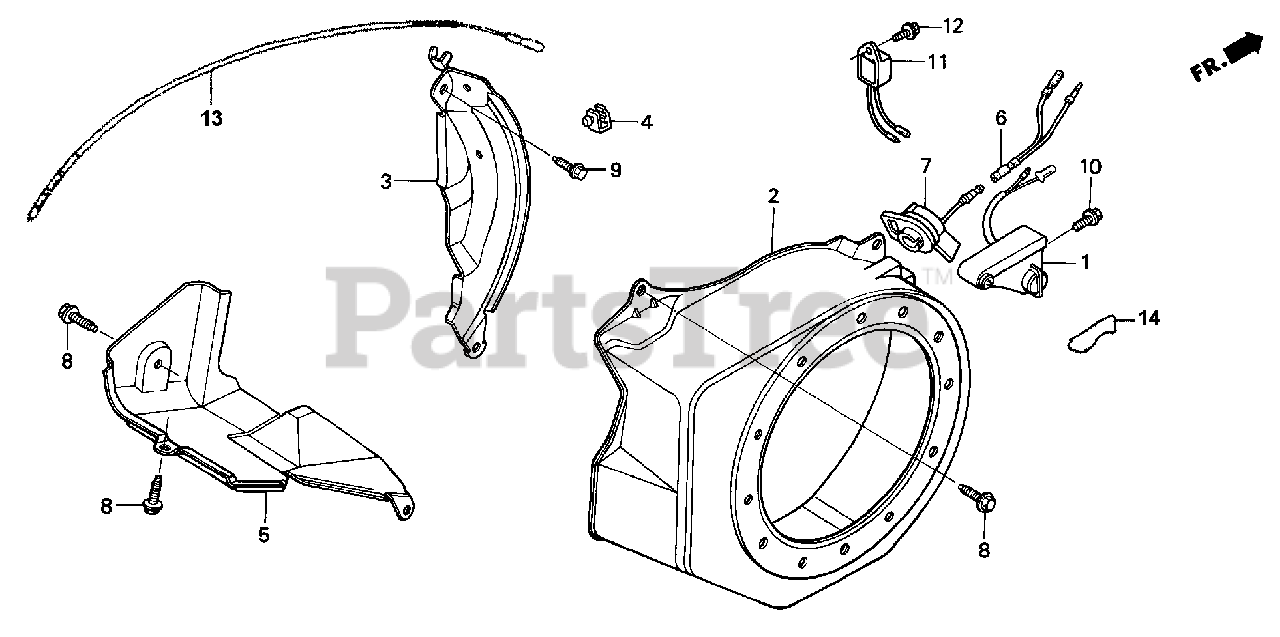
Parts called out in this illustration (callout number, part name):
1	ALERT UNIT, OIL
2	COVER, FAN *R8* (BRIGHT RED)
2	COVER, FAN *R280* (POWER RED)
2	COVER, FAN *R8* (OIL ALERT) (BRIGHT RED)
2	COVER, FAN *R280* (OIL ALERT) (POWER RED)
3	PLATE, SIDE (OIL ALERT)
3	PLATE, SIDE
4	CLAMP, CORD
4	CLIP, HARNESS
5	SHROUD
6	SUB-HARNESS
7	SWITCH ASSY., ENGINE STOP
8	BOLT, FLANGE (6X12) (CT200)
9	BOLT, FLANGE (6X20) (CT200)
10	BOLT, FLANGE (6X8)
11	ALERT UNIT, OIL
12	BOLT, FLANGE (6X8)
13	WIRE, STOP SWITCH (370MM)
14	MARK, OIL ALERT (EXTERNAL)
